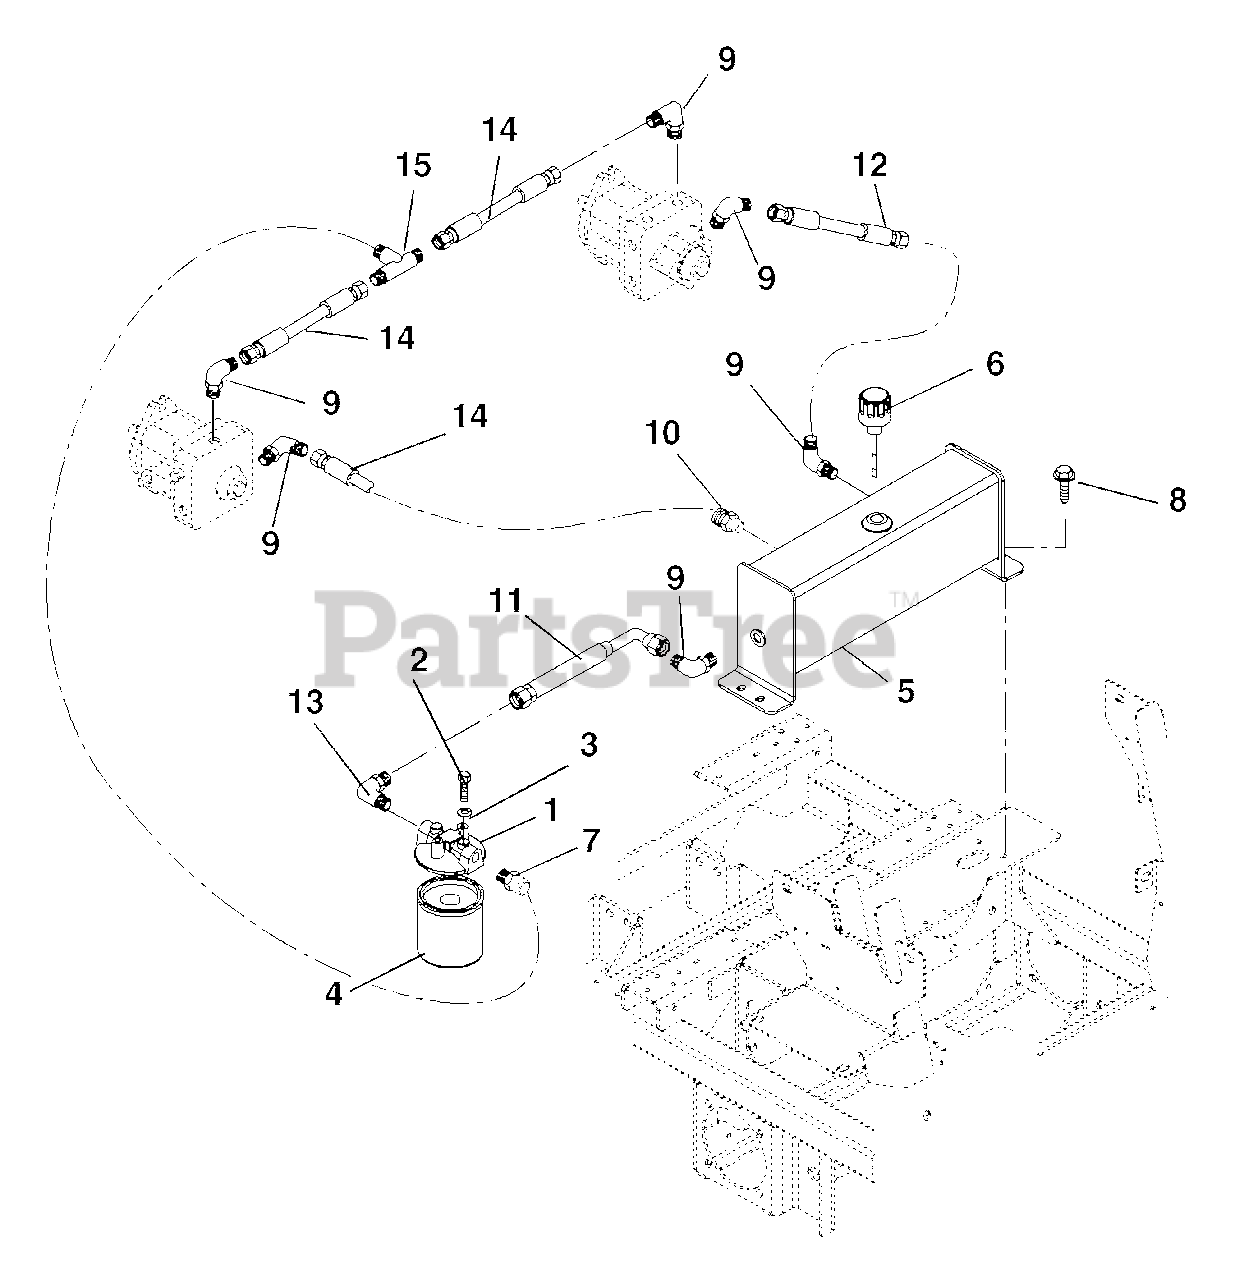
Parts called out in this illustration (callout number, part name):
1	Filter Housing
2	Bolt-Hex .25-20 x .50 Grade 5
3	Washer-Locking .25 x .062
4	Filter Element
5	Body, Hydraulic Tank
6	Breather, Dipstick
7	Adapter-Hydraulic Steel
8	Screw-Tapping .38-16 x .75 Hex Washer Head
9	Adapter, Hydraulic Elbow
10	Adapter, Hydraulic Steel
11	Hose-Hydraulic Valve to Tank
12	Hose, Hydraulic
13	Adapter, Elbow 90 Degree
14	Hose, Hydraulic .50
15	Fitting Hydraulic Tee
